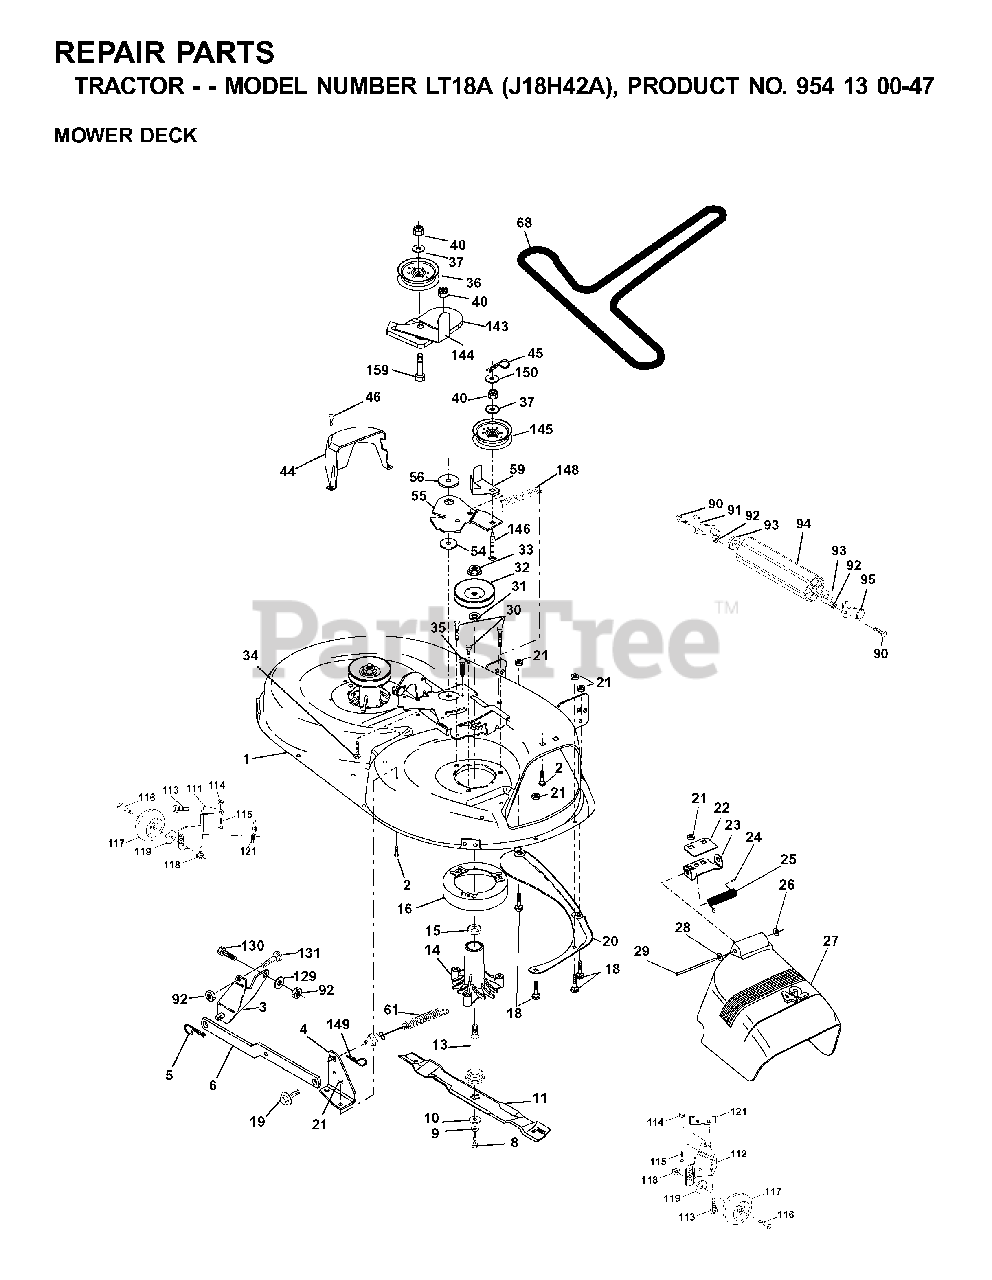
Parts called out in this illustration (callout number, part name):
1	42" DECK KIT
2	BOLT
3	BRKT ASM SWAY BAR
4	BRACKET SWAY BAR 42" DECK
5	RETAINER-SPRNG RB
6	REAR SUSP ARM
8	BLADE BOLT
9	LOCKWASHER
10	WASHER.BLADE
11	BLADE 42"
13	SHAFT ASM VENT
14	HSG MANDREL
16	STRIPPER
18	BOLT
19	BOLT SHD 5/16-18
20	BAFFLE.VORTEX
21	LOCKNUT
22	STIFFENER BRACKET
23	DEFLECTOR BRACKET
24	CAP-SLEEVE LT
25	SPRING TORSION
26	NUT PUSH M
27	SHIELD DEFLECTOR
28	WASHER
29	ROD.HINGE
30	SCREW THDROL ROLLING WASHER HD
31	WASHER
32	PULLEY/MANDREL
33	NUT
34	BOLT
35	FASTENER.XMAS.TREE
36	FLAT IDLER PULLEY
40	LOCKNUT
44	GUARD MANDREL LH BLACK
45	RETAINER M
46	SCREW.1/4-20X5/8
54	HARDENED WASHER
55	ARM IDLER 42" MOWER LT/YT
56	SPACER.RETAINER.MOWER
59	GUARD, BELT
61	SPRING EXT ELEC CLUTCH
68	BELT V SECONDARY
90	BOLT
91	BRACKET LH (A)
92	NUT
94	NOSE ROLLER
95	BRACKET RH (B)
111	BRACKET WHEEL GAUGE LH 42" DK
112	BRACKET WHEEL GAUGE RH 42" DK
114	NUT
115	BOLT
117	WHEEL.GAUGE.STANDARD
118	LOCKNUT
119	WASHER
121	BRACKET.EXTRD.GWL
129	WASHER
131	BOLT D
143	BRACKET, ARM IDLER
144	KEEPER.BELT.42".CLUTCH.CABLE
145	PULLEY
146	BOLT, CARRIAGE IDLER BLACK
148	IDLER RETURN SPRING
149	SPRING.RETAINER.YELLOW.ZINC
150	WASHER PM
159	BOLT
